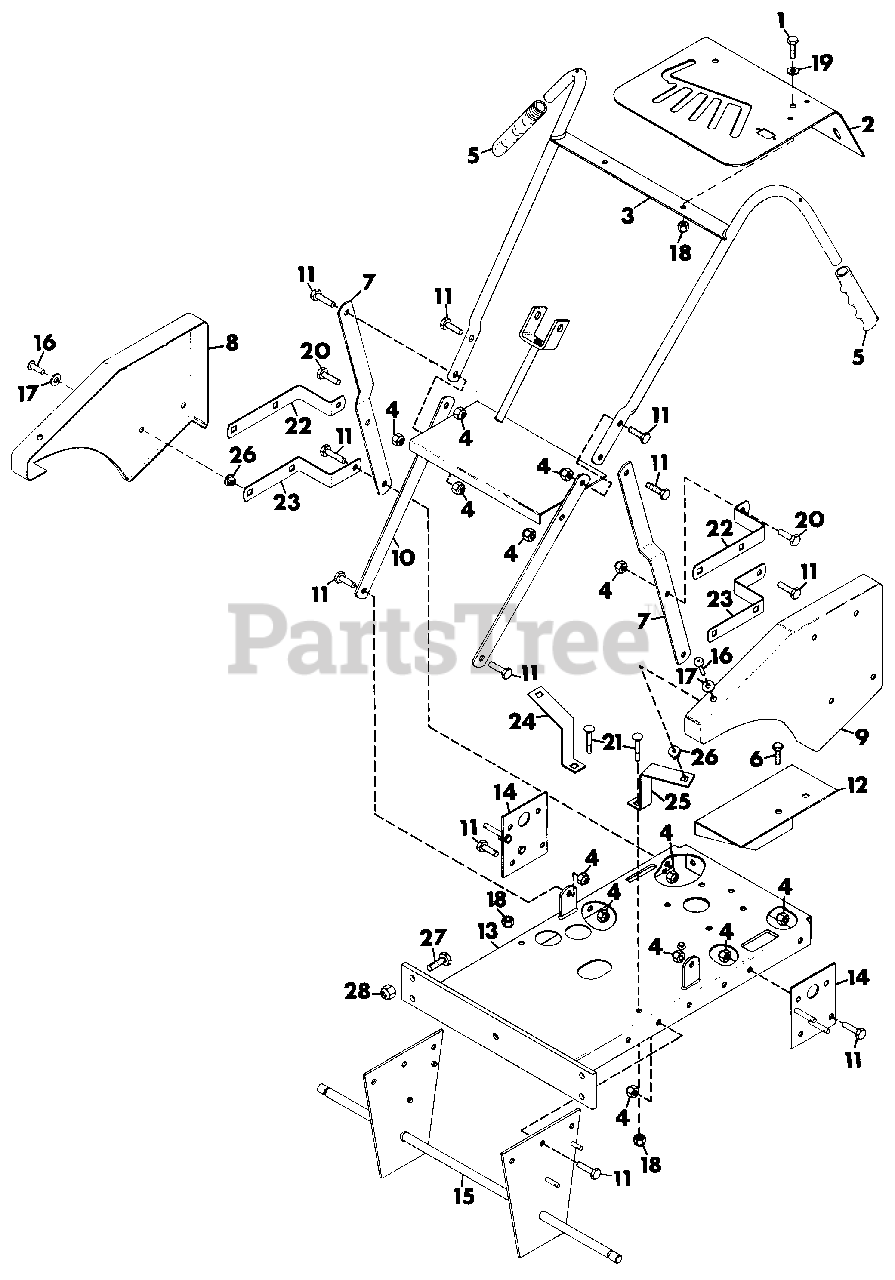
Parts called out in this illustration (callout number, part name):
1	BOLT, HEX 5/16-18X1.00
2	PLATE, INSTRUCTION
3	WELDMENT, HANDLEBAR
4	NUT, LOCK 3/8-16
5	GRIP, HAND
6	BOLT, SELF-TAPPING 5/16-18X.50
7	BRACE, HANDLEBAR SUPPORT
8	GUARD, BELT R.H.
9	GUARD, BELT L.H.
10	WELDMENT, HANDLE BAR SUPPORT
11	BOLT, HEX 3/8-16X1.25
12	GUARD, TRANSMISSION CHAIN
13	WELDMENT, FRAME
14	WELDMENT, BEARING SUPPORT L.H.
15	WELDMENT, AXLE
16	SCREW, MACHINE 1/4-20X.625 RD HD
17	WASHER, FLAT .281X.625X.065
18	NUT, LOCK 5/16-18
19	WASHER, FLAT .344X.688X.065
20	BOLT, HEX 3/8-16X.75
21	BOLT, HEX 5/16-18.75
22	BRACKET, TOP
23	BRACKET, BOTTOM
24	SUPPORT, FRONT R.H.
25	SUPPORT, FRONT L.H.
26	GROMMET, PLASTIC
27	BOLT, HEX 1/2-13X1.50
28	NUT, LOCK 1/2-13
